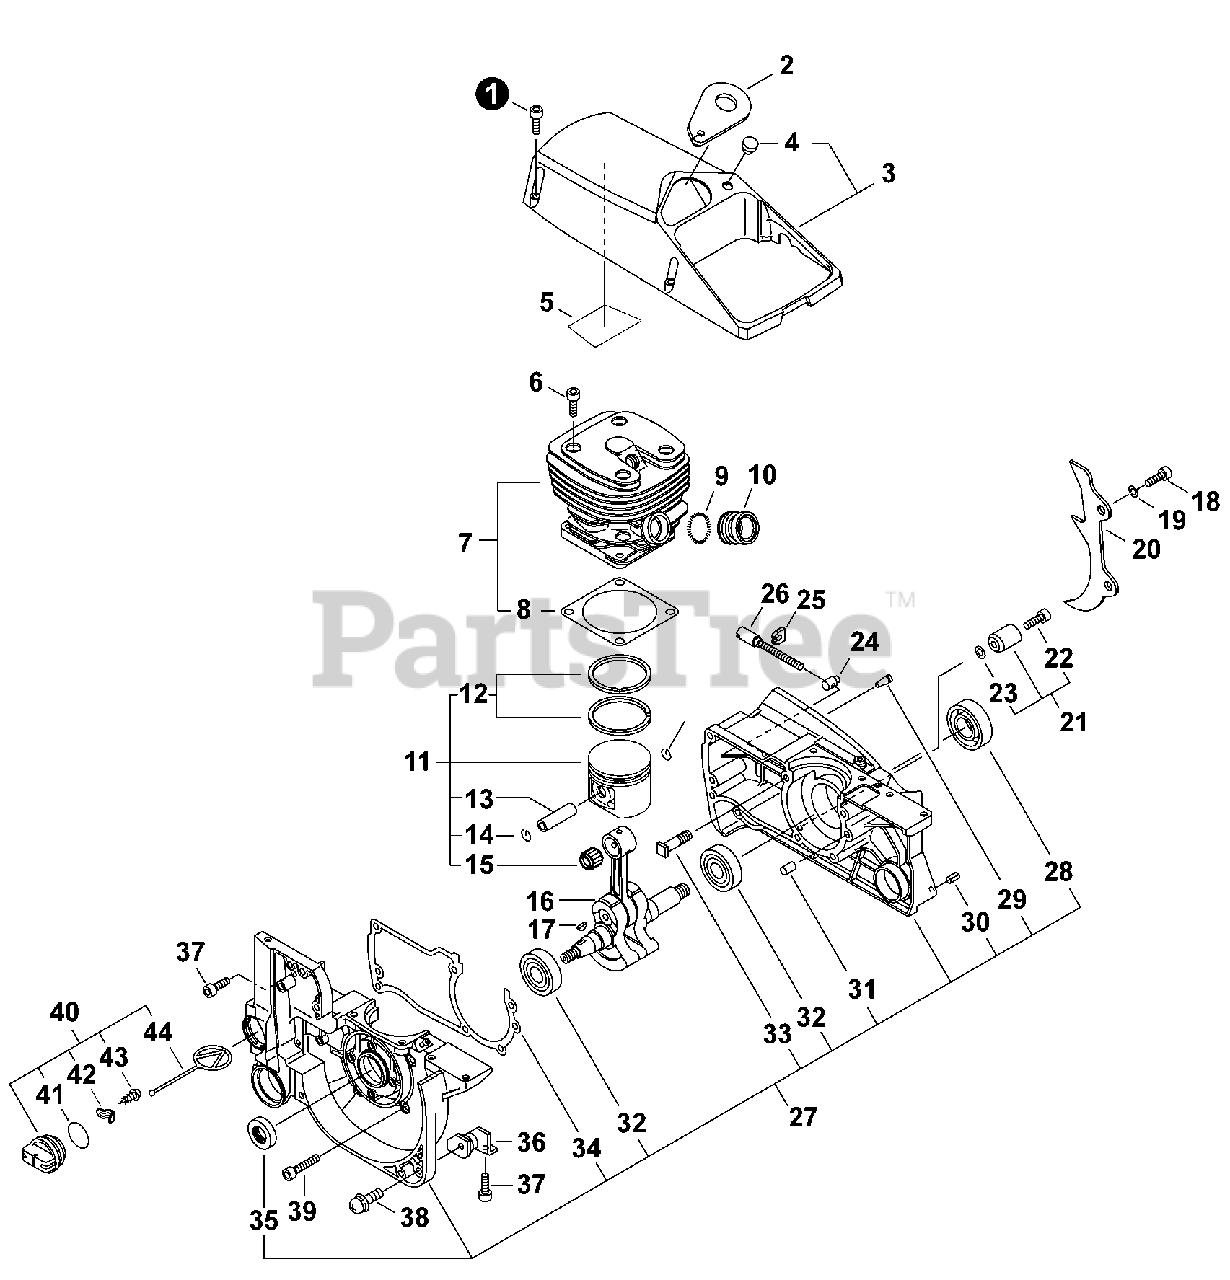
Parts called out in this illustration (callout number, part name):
1	BOLT 5×20
2	PLATE, GUIDE
3	COVER KIT, ENGINE
5	SHIELD, HEAT
6	BOLT 6×25
7	CYLINDER ASSY
8	GASKET, CYLINDER
10	ADAPTOR, INTAKE
11	PISTON KIT
12	RING, PISTON
13	PIN, PISTON 8×13×38.8
14	RING, RETAINING
15	BEARING, NEEDLE
16	CRANKSHAFT
17	KEY, WOODRUFF
18	BOLT 6×20
19	WASHER, SPRING 6
20	SPIKE, BUMPER
21	CHAIN CATCHER KIT
22	BOLT 5×20
23	WASHER, FLAT 5.5×10×0.8
24	TENSIONER, CHAIN
26	SCREW, ADJUSTER
27	CRANKCASE KIT
28	SEAL, OIL
29	VENT ASSY
30	PIN, SPRING 5×10
31	PIN, LOCATING 5×10
32	BEARING, BALL 6203 C3
33	STUD, GUIDE BAR 8
34	GASKET, CRANKCASE
35	SEAL, OIL
37	BOLT 5×20
38	SCREW 5×14
39	BOLT 5×35
40	CAP ASSY, OIL
41	O-RING 25
42	RETAINER, CONNECTOR
43	SCREW, TAPPING 3×8
44	CONNECTOR, CAP L=60mm
